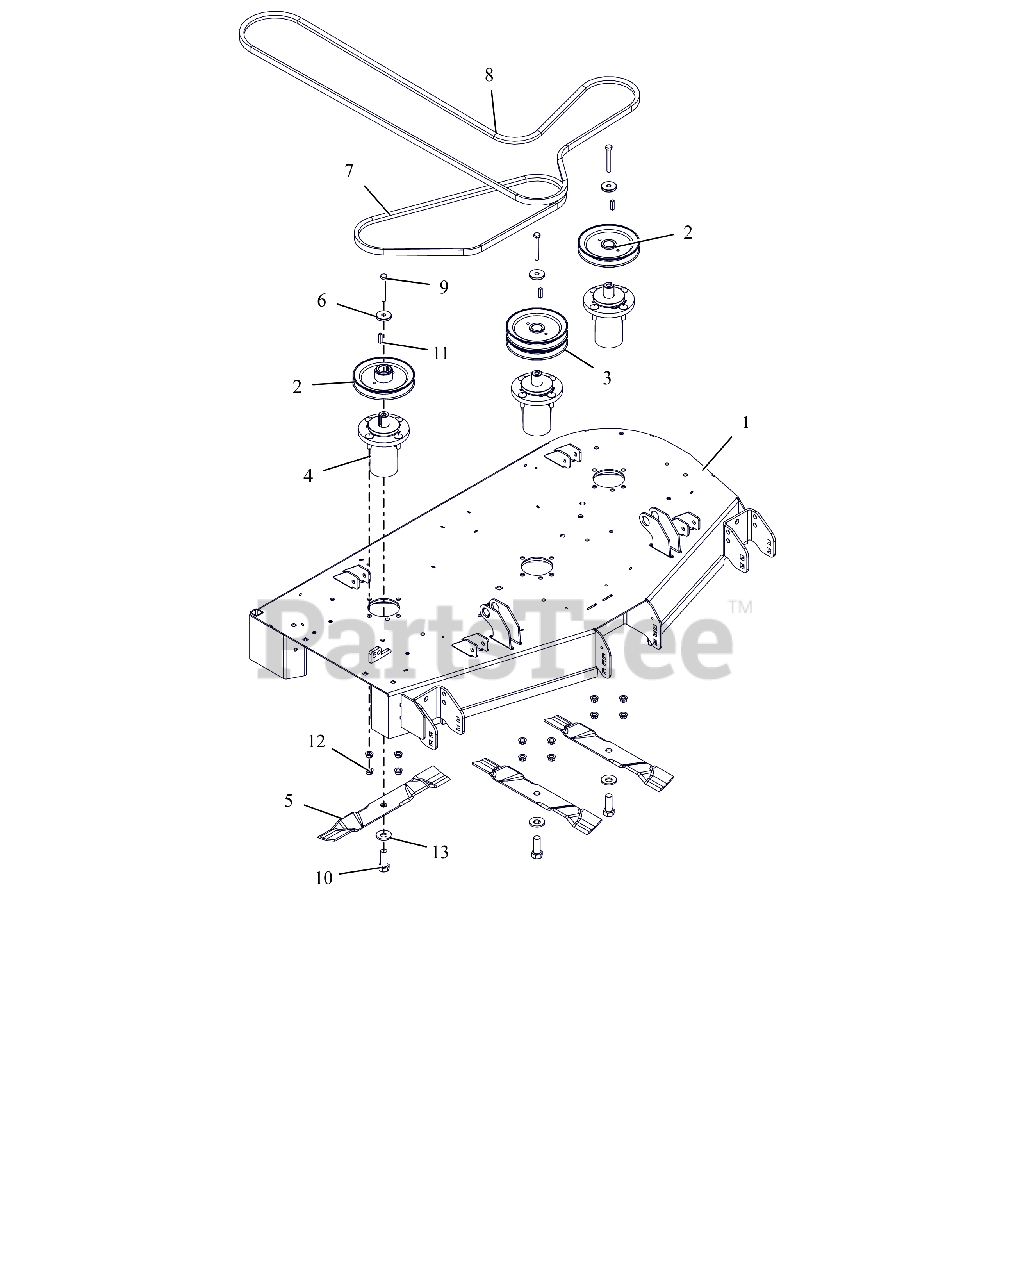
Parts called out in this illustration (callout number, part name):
1	WLDMT, 48'' CE SIDE DISCH DECK (ORANGE)
2	PULLEY, SINGLE-1"ID X 6" OD
3	PULLEY, DOUBLE
4	ASM, MAINT FREE ALUM SPINDLE
5	BLADE, MULCH 16.25
6	RETAINER, SHEAVE
7	V-BELT, B-COGGED
8	V-BELT, HB SECTION
9	BLT-HEX .38-16X2.75 GR8 YWZC
10	BLT-HEX .62-18X1.75 GR8 YWZC
11	KEY, SQ .25X.25X1.00 RC 40-50
12	NUT-LK-CTR-FLG .38-16 YWZC
13	WSHR-BLVL .669X1.535X.138
